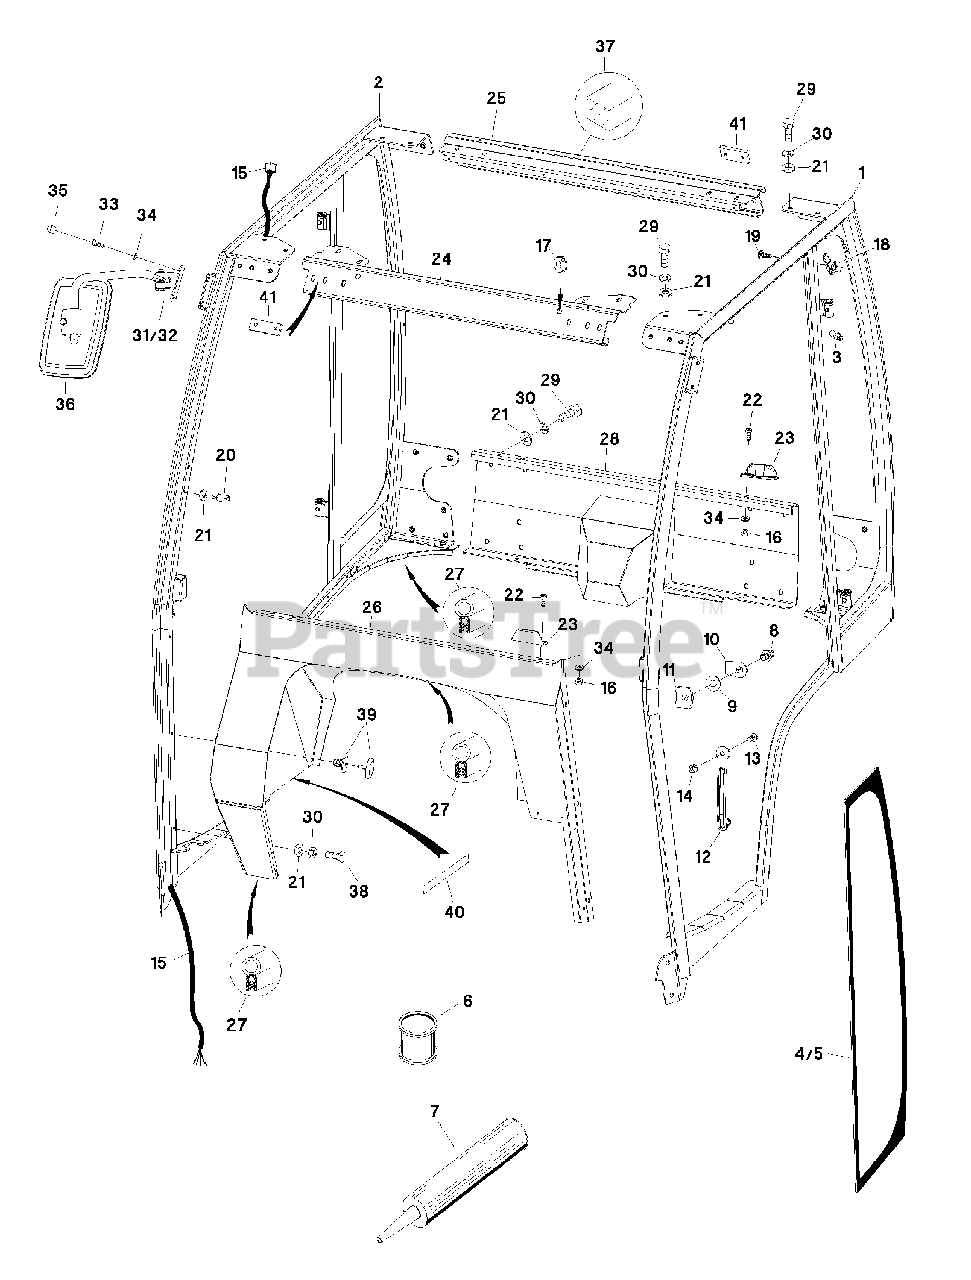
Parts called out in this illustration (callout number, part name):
1	Side frame left
2	Side frame right
3	Impact nipple H1 d=6mm
4	Glass SH left
5	Glass SH right
7	Adhesive for panel (Sikadrive)
8	Locking pin 13mm
10	Slide-off strap
11	Threaded plate
12	Door push-out
13	Countersunk head screw M8x20
14	Stop nut M8
16	Stop nut M6
17	Blind plug 18mm
19	Sheet metal screw 3.9x13
20	Pneumatic spring sleeve l=22mm / 2x M8
21	Shim disk M8
22	Oval head screw M6x16 cross-recessed
23	Locking device
24	Cross-strut front above
25	Cross-strut rear above
26	Front panel
27	Tube profile
29	Hexagon head screw M8x20
30	Retainer ring
31	Mirror left complete 602001 (Includes Ref. No. 36)
32	Mirror left complete 602001 (Includes Ref. No. 36)
33	Hexagon head screw M6x16
34	Shim disk M6
35	Cover cap d=6mm
36	Mirror
37	Compriband A20/15
38	Hexagon head screw M8x12
39	Expansion rivet
40	Velour band
41	Distance plate hinge t=8mm
